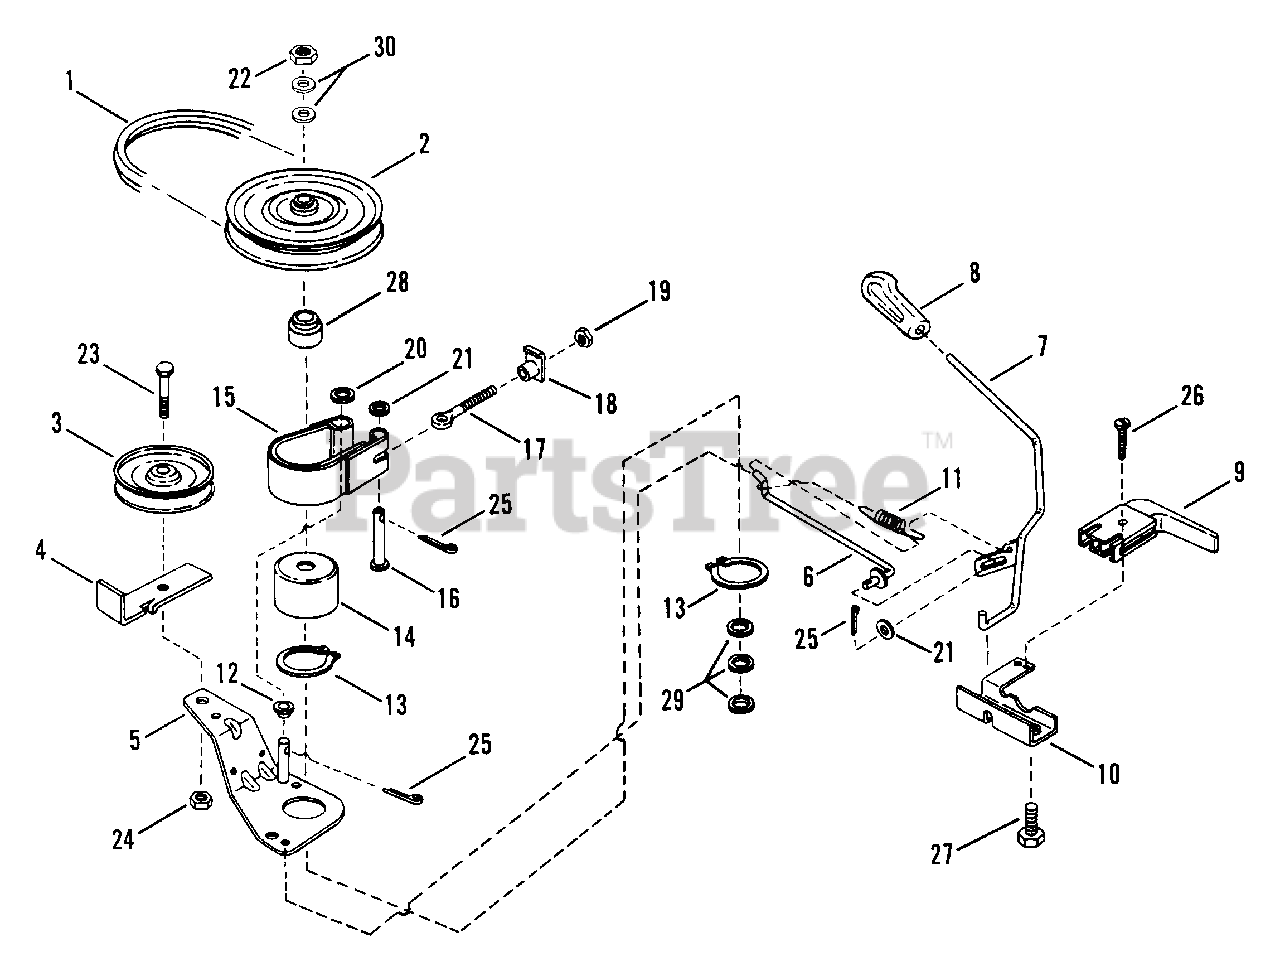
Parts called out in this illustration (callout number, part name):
1	BELT, Drive
2	PULLEY, Spindle
3	PULLEY, Idler
4	RESTRICTOR, Belt
5	ARM, Idler
6	ROD, Idler
7	HANDLE, Blade Lever (On-Off)
8	GRIP, Handle
9	SWITCH, Deck lnterlock
10	MOUNT, Handle
11	SPRING, Blade Handle
12	SPACER
13	RING, 2" External Retaining
14	DRUM, Brake
15	BAND, Brake Assembly
16	PIN, 1/4 x 1-5/8" Clevis
17	BOLT, 1/4-20 Eye
18	NUT, 1/4-20 Tee
19	NUT, 1/4-20 Hex
20	WASHER, 3/8" Flat
21	WASHER, 1/4 Flat
22	NUT, 3/4-16 Hex Jam
23	SCREW, 3/8-24 x 1-3/4" Hex Cap
24	NUT, 3/8-24 Hex Lock
25	PIN, 3/32 x 3/4" Cotter
26	SCREW, #10-32 x 1" Self-Tap
27	SCREW, 1/4-20 x 5/8" Self-Tap
28	HUB, Pulley
29	WASHER, 49/64 x 1-1/8" Flat
30	WASHER, 49/64 x 1-1/2" Flat
